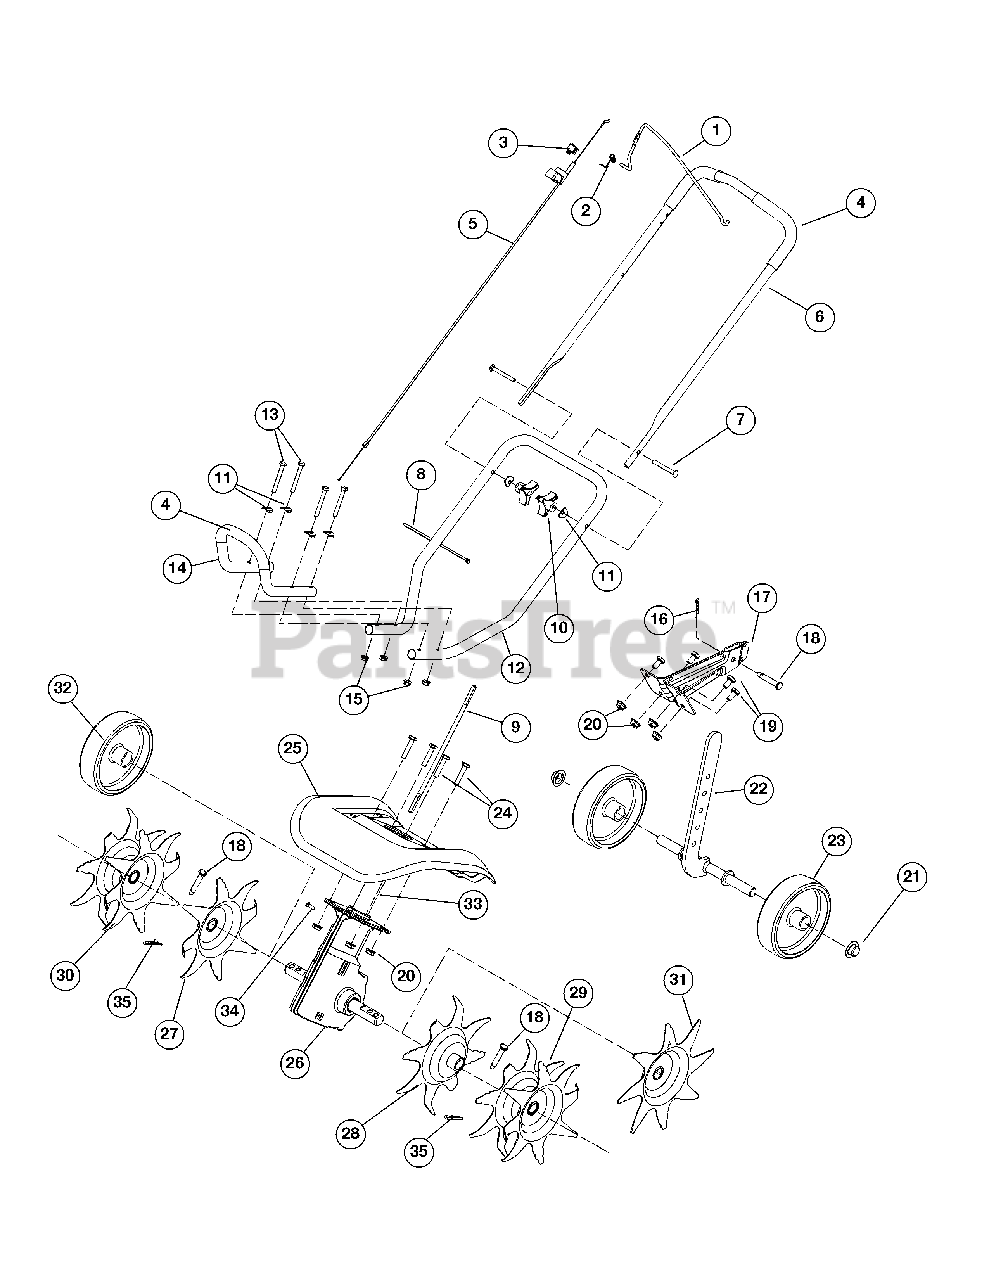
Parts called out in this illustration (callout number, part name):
1	Throttle Control
2	Torsion Spring
3	On/Off Switch
4	Foam Grip
5	Throttle Cable
6	Upper Handle
8	Cable Tie
9	Flex Shaft
11	Washer
13	Screw
14	Front Handle
16	Cotter Pin
17	Tailpiece Bracket Assembly
18	Clevis Pin
19	Cap Screw
22	Wheel Support Bracket Assembly
23	Wheel
25	Tine Shield
26	Gear Box Assembly
27	Tine (Right Inner)
28	Tine (Left Inner)
29	Tine (Left Outer)
30	Tine (Right Outer)
31	Edger Tine
32	Edger Wheel
33	Drive Shaft Housing
34	Sleeve Retaining Bolt
